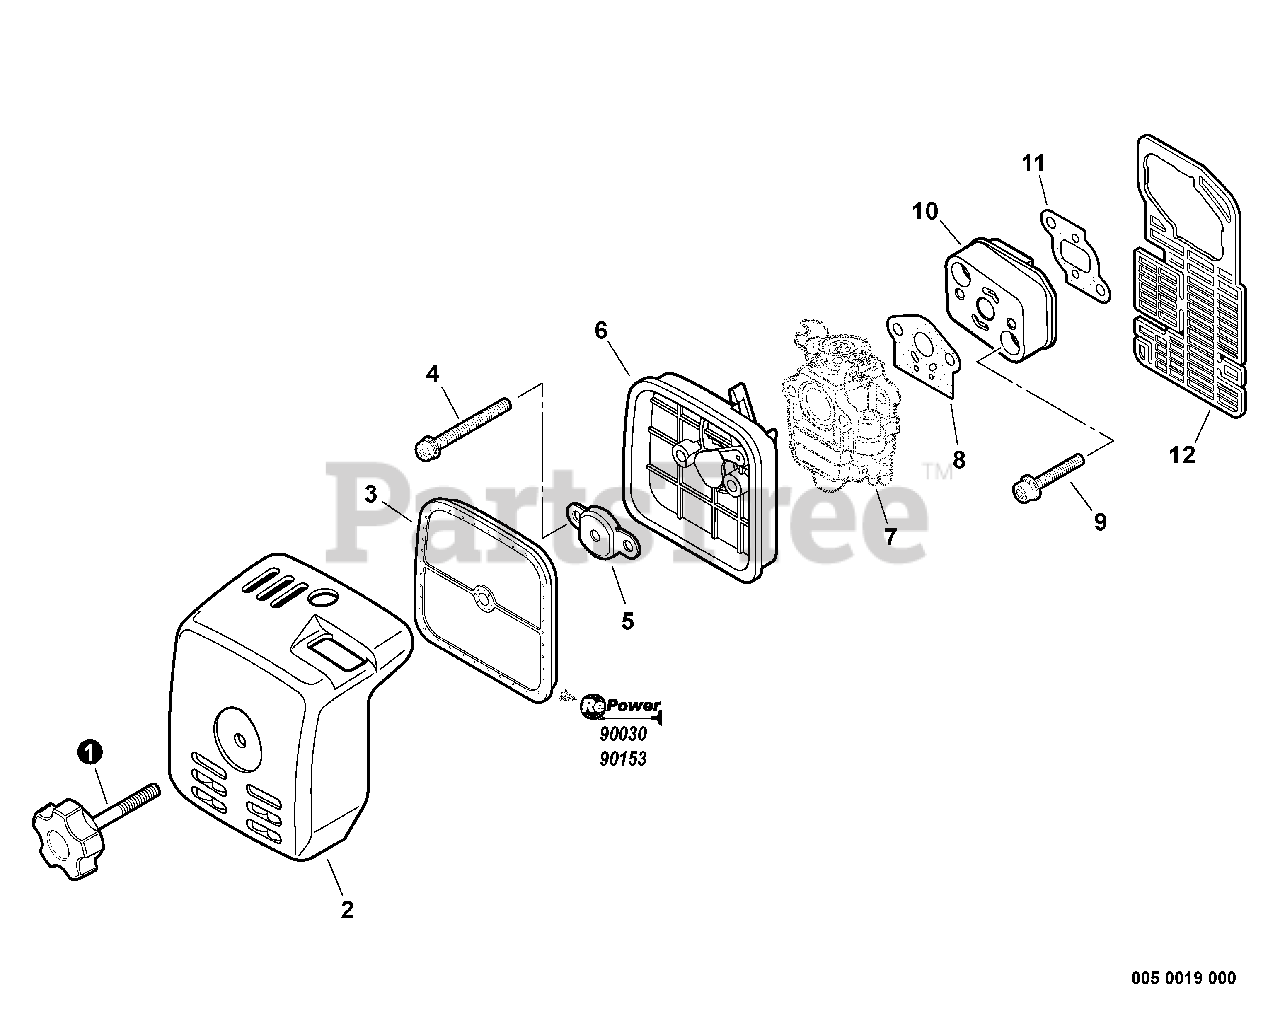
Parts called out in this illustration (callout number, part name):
1	THUMBSCREW
2	COVER, AIR FILTER
3	FILTER, AIR - HEAVY DUTY
4	SCREW - 5X60
5	PLATE, PREVENT
6	CASE, AIR FILTER
7	CARBURETOR
8	GASKET, INTAKE
9	SCREW - 5X25
10	INSULATOR, INTAKE
11	GASKET, INTAKE
12	GUARD, DEBRIS
13	RePower FILTER KIT
14	RePower TUNE-UP KIT
